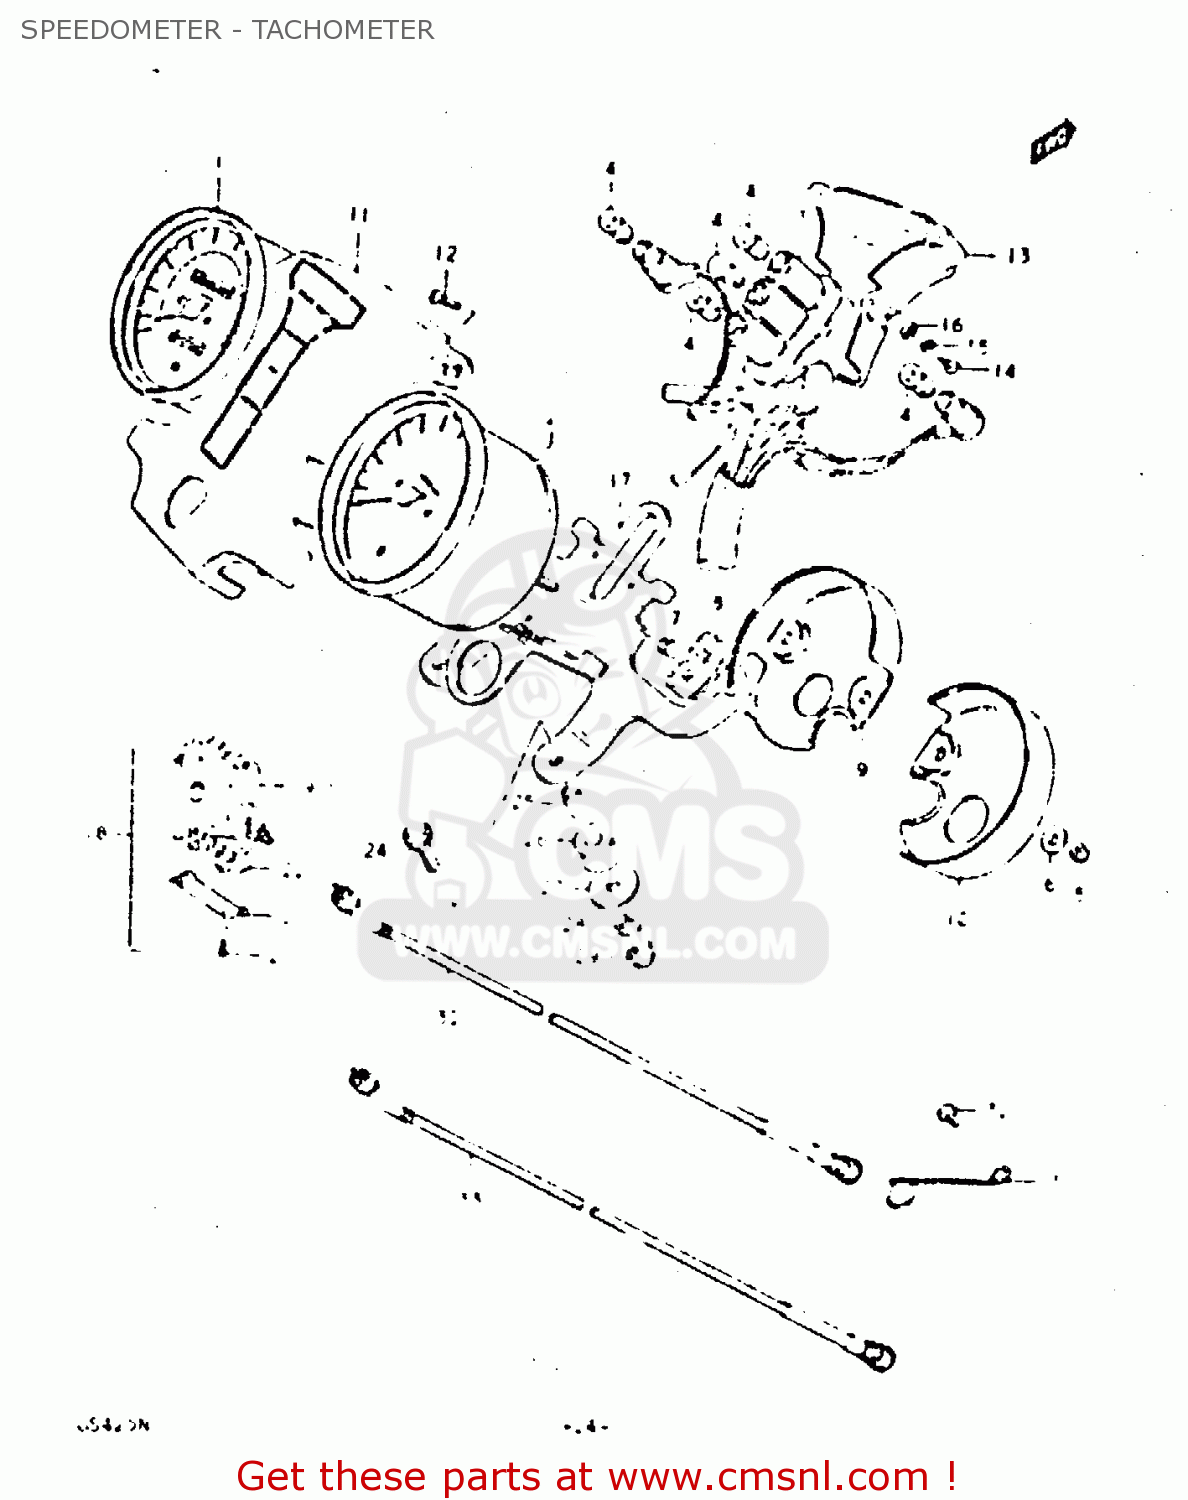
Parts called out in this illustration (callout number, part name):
1	SPEEDOMETER
2	TACHOMETER
3	SOCKET,METER
4	BULB(12V3.4W,STANLEY,A72A)
5	NUT
6	WASHER (5.5X16X1.2)
7	SPACER
8	CUSHION,METER
9	UNDER COVER,SPEEDOMETER
10	UNDER COVER,TACHOMETER
11	CASE,PILOT BULB
12	SCREW
13	COVER,PILOT BULB CASE
14	SCREW(4X16)
15	WASHER,PILOT UNDER CASE
16	WASHER
17	BRACKET,METER
18	INDICATOR ASSEMBLY,GEAR POSITION
19	CASE,GEAR INDICATOR
20	COVER,LWR
21	SCREW,GEAR INDICATOR
22	SOCKET,GEAR INDICATOR
23	SCREW
24	BOLT
25	SPACER (6.1X8X15.5)
26	CUSHION
27	WASHER
28	LOCK WASHER
29	NUT
30	CABLE ASSEMBLY,SPEEDOMETER
31	GUIDE,SPEEDOMETER CABLE
32	BOLT, UPPER
33	CABLE ASSEMBLY,TACHOMETER
